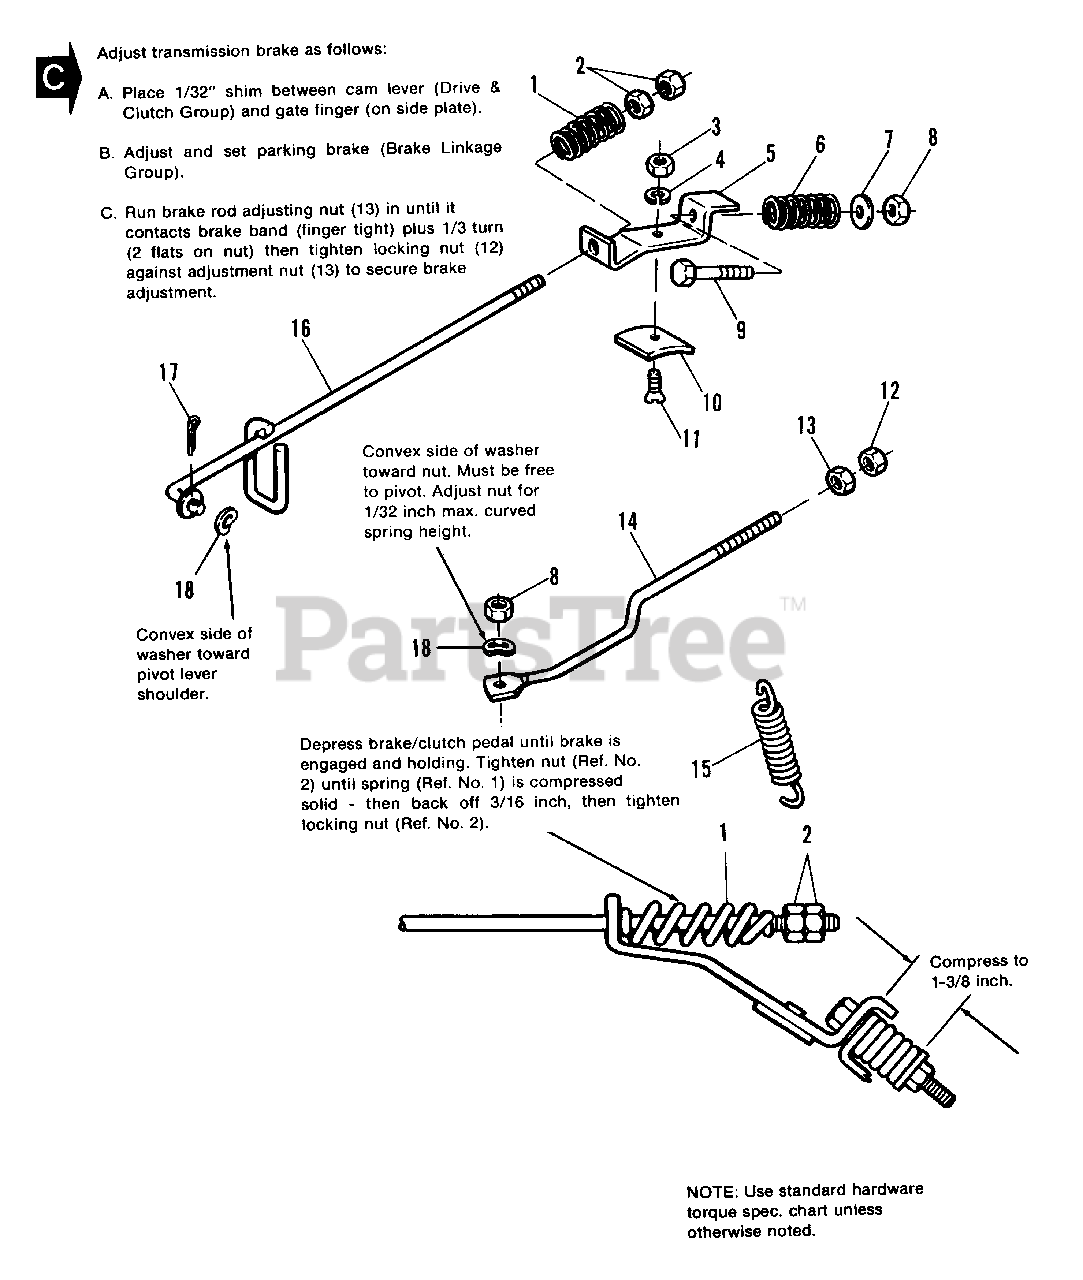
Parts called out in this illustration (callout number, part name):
2	NUT, Hex, Full, 5/16-18
3	NUT, Hex, Full, #10-24
4	LOCKWASHER, #10
7	WASHER, 1/4
8	LOCKNUT, Hex, 5/16-18
9	CAPSCREW, Hex Hd., 5/16-18 x 2-1/2
10	BRAKE, Sheave
11	SCREW, Machine, #10-24 x 5/8
12	LOCKNUT, Hex, Esna, 3/8-16
13	NUT, Hex, Full, 3/8-16
14	ROD, Brake
16	ROD ASSY., Pulley Brake
17	PIN, Cotter, 3/32 x 1/2
18	WASHER, Curved Spring
